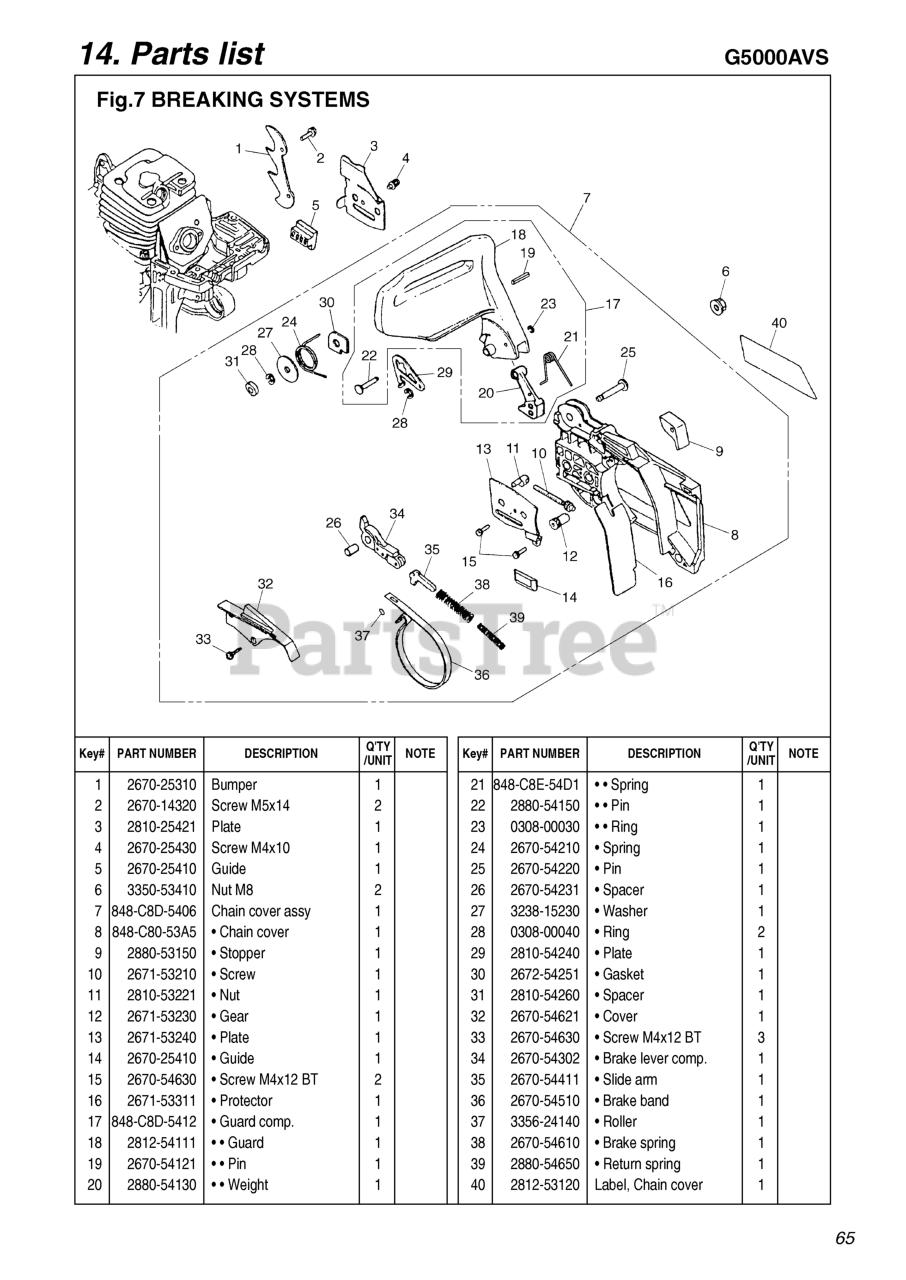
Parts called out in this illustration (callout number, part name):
1	SPIKE
2	SCREW (REPLACES 2616-24320)
3	PLATE (REPLACES 2670-25422)
5	GUIDE, CHAIN
6	NUT
7	CHAIN COVER ASSY
8	COVER, CHAIN (RPLS.2671-53114)
9	STOPPER
10	SCREW
11	NUT
12	GEAR
14	GUIDE, CHAIN
15	SCREW
16	PROTECTOR
17	GUARD COMP (RPLS 2812-54101)
18	GUARD (RPLS 2672-54110)
19	PIN, STOPPER
20	WEIGHT, ACTION
21	SPRING (RPLS. 2880-54140)
22	PIN, SPRING
23	RING, SNAP, M3
24	SPRING, RETURN
25	PIN
27	WASHER
28	RING, SNAP, M4
29	PLATE (RPLS 2670-54241)
30	GASKET (RPLS 2672-54250)
32	COVER (REPLACES -54620)
33	SCREW
34	LEVER (REPLACES 2670-54301)
35	ARM, SLIDE(RPLS 2670-54410)
36	BAND, BRAKE
37	PIN
38	SPRING, BRAKE (RPLS. 50030121)
40	LABEL, CHAIN COVER
